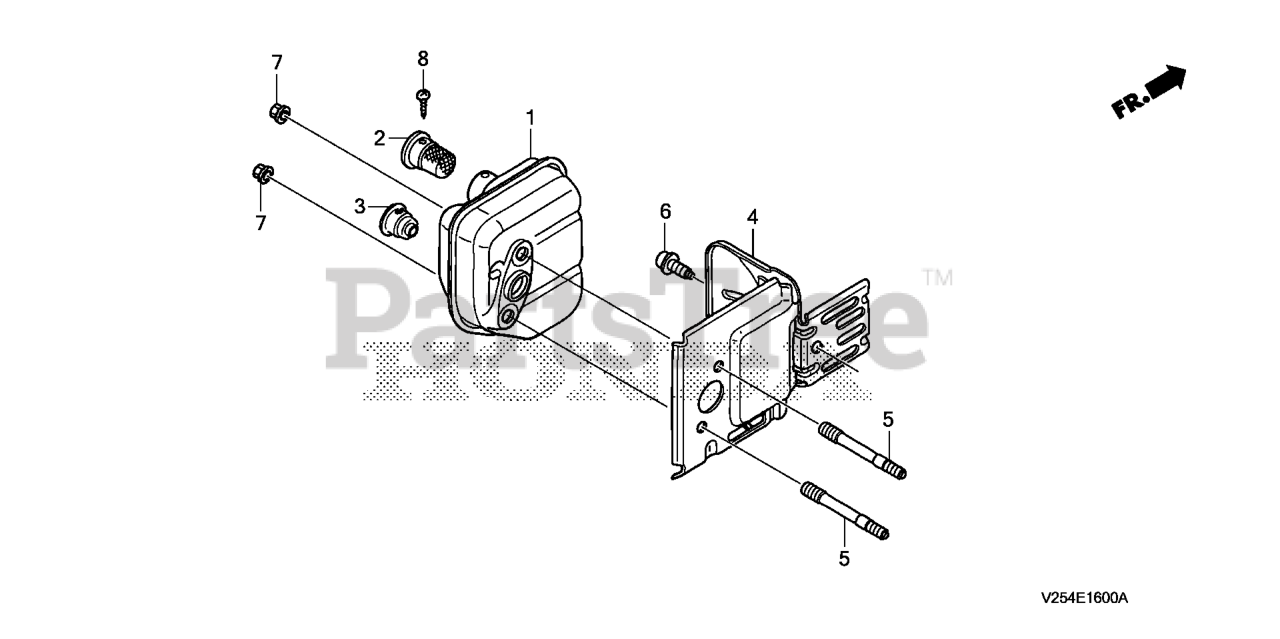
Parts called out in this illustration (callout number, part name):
1	MUFFLER
1	MUFFLER (ARRESTER)
2	ARRESTER, SPARK
3	FLANGE, BAFFLE
4	GUIDE, AIR EX.
5	BOLT, STUD (5X52)
6	BOLT, SOCKET (5X10)
7	NUT, SELF-LOCK (5MM)
8	SCREW, TAPPING (3X6)
